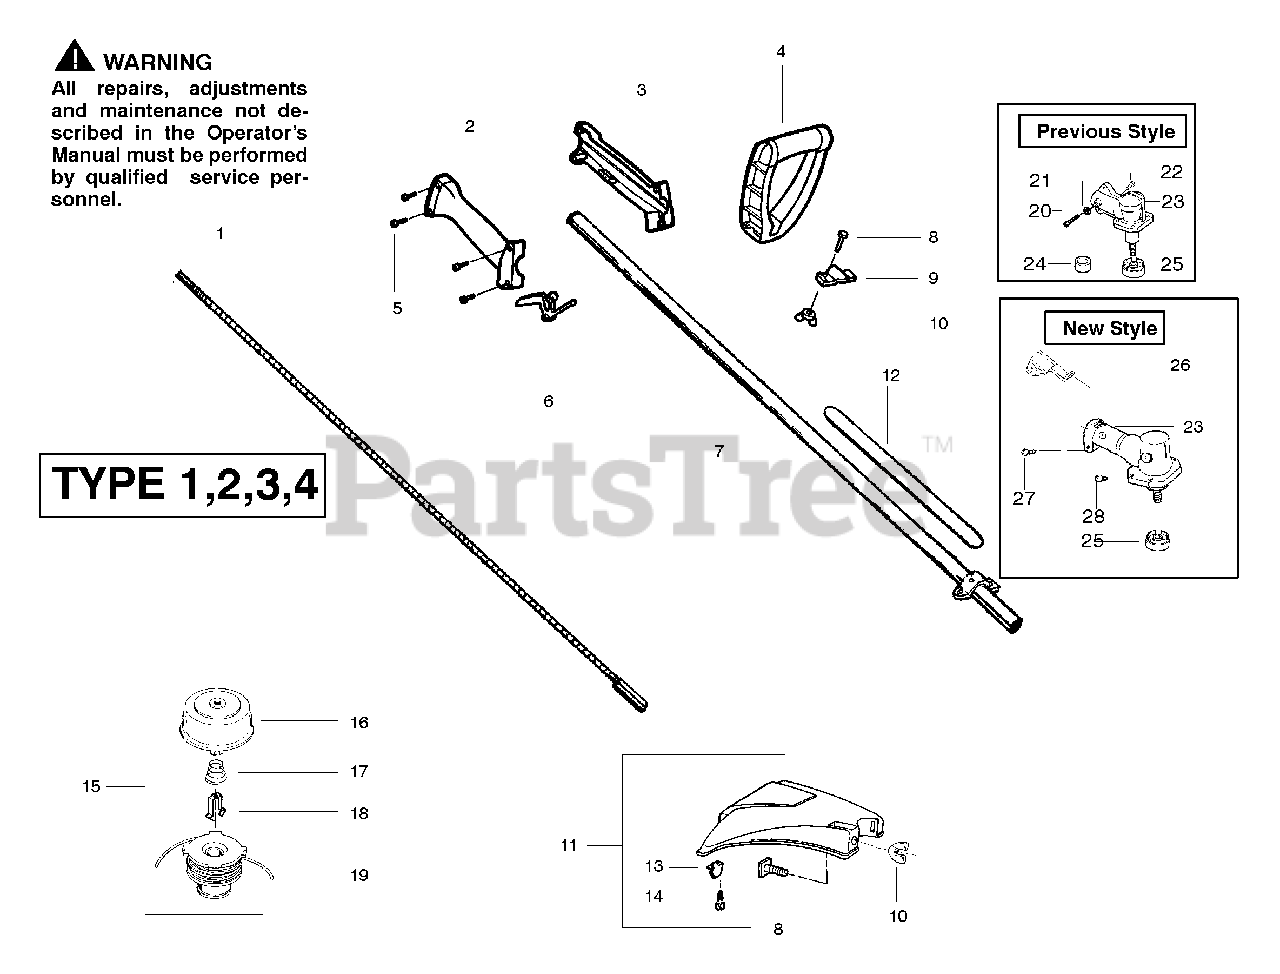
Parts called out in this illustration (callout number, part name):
1	Shaft-Flex-52"
2	Throttle Hsg. (Right)
3	Throttle Hsg. (Left)
4	Assist Handle
5	Screw-Throttle Hsg.
6	Trigger Lever
7	Assy-Drive Shaft ( Type 1,2,3 )
7	Assy-Drive Shaft ( Type 4 )
9	Clamp-Handle
10	Wingnut
11	Shield Kit Ass'y.
12	Shaft Warning Decal
13	Line Limiter
14	Screw-Line Limiter
15	Accy-Cutting Head Ass'y.
16	Hub Ass'y.
17	Spring-Return
18	Retainer-Spool
19	Spool w/Line
20	Screw-Gear Box
21	Lockwasher-Gear Box
22	Screw-Gear Box/Shield
23	Assy-Gear Box
24	Seal Sleeve
25	Dust Cup (Type 4 )
